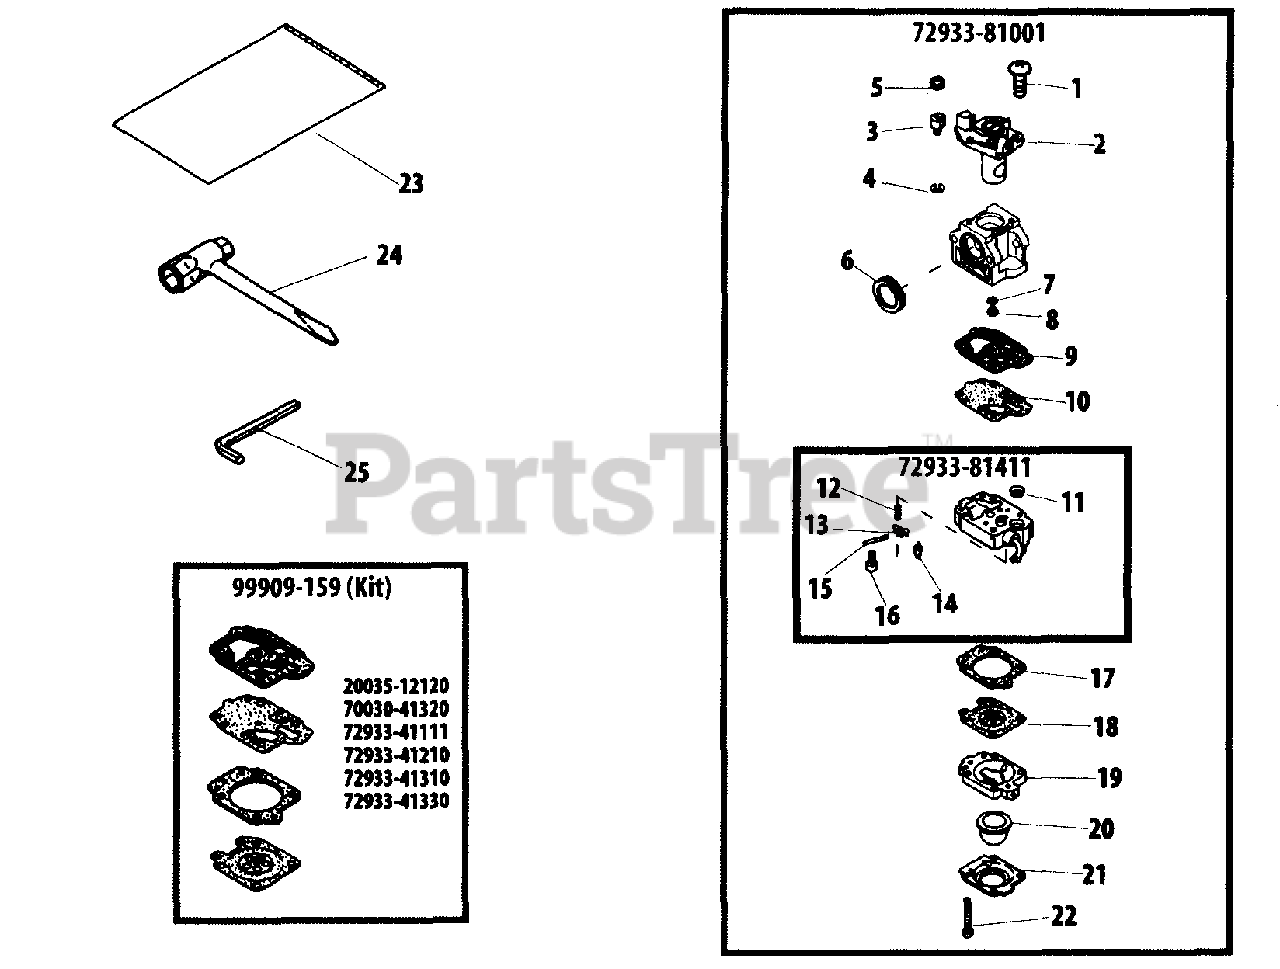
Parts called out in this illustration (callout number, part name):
1	SCREW
2	THROTTLE VALVE ASSY
3	SWIVEL
4	RING, RETAINING
5	RING, RETAINING
6	SEAL
7	O-RING
8	JET, MAIN - 43
9	GASKET, PUMP
10	DIAPHRAGM, PUMP
10	BASE, PURGE
11	STRAINER
12	SPRING, METERING LEVER
13	LEVER, METERING
14	VALVE, INLET NEEDLE
15	PIN, METERING LEVER
16	SCREW, METERING LEVER PIN
17	GASKET, METERING
18	DIAPHRAGM, METERING
19	BASE, PURGE
20	BULB, PURGE
21	RETAINER, PURGE BULB
22	SCREW, PUMP COVER
23	BAG, TOOL
24	T-WRENCH - 13X19mm
25	HEX KEY - 4mm
